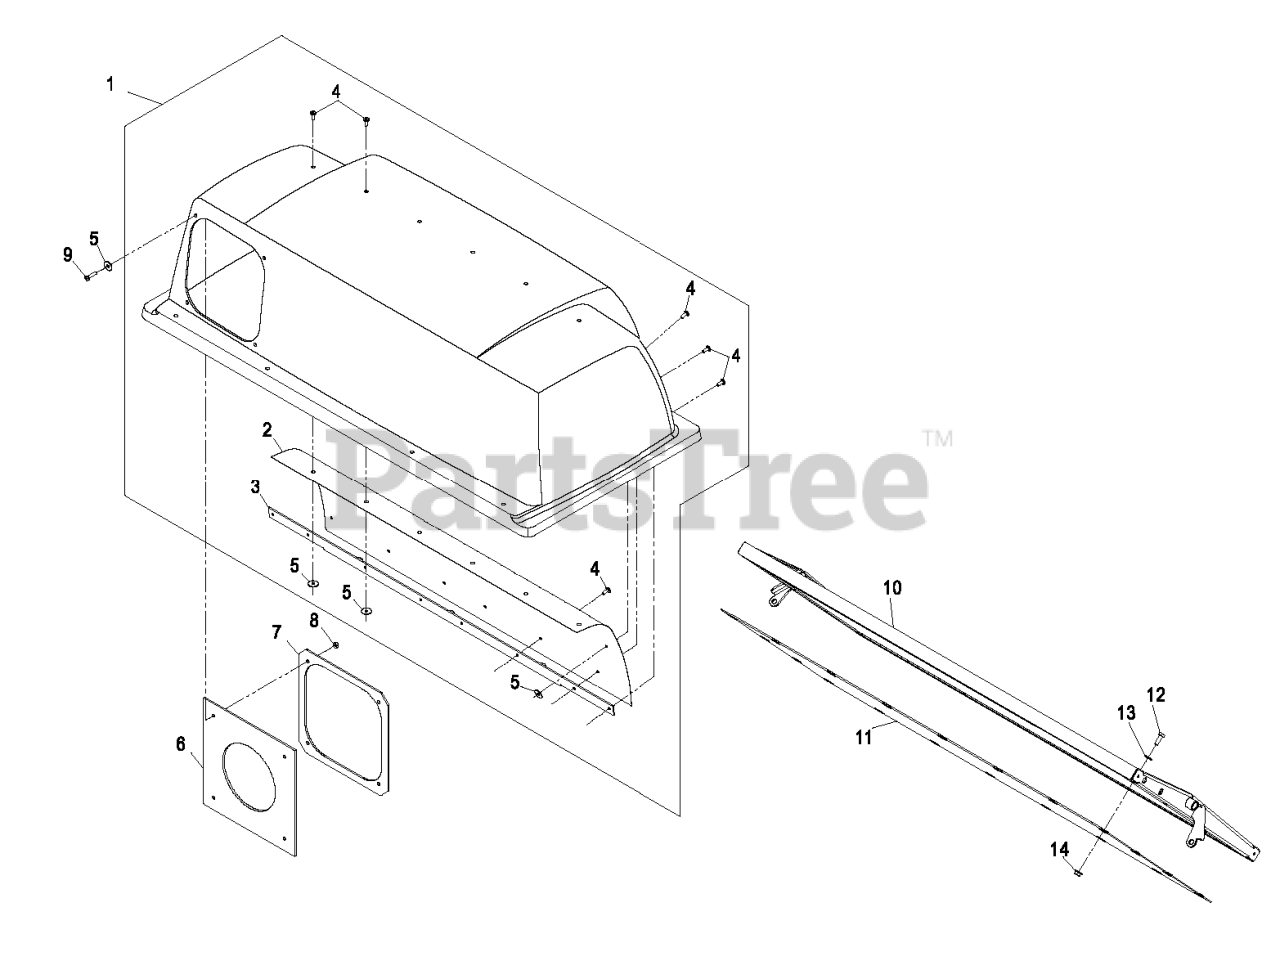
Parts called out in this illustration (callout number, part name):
1	ASM, HOOD
2	SCREEN-BAGGER
3	SUPPORT-SCREEN
4	RIVET-BLIND
5	WASHER-FLAT
6	SEAL-CHUTE
7	CLAMP-SEAL
8	NUT-LOCK, NI
9	SCREW-PPH
10	DOOR-FRAME
11	SCREEN-DOOR
12	SCREW-HH
13	WASHER-FLAT
